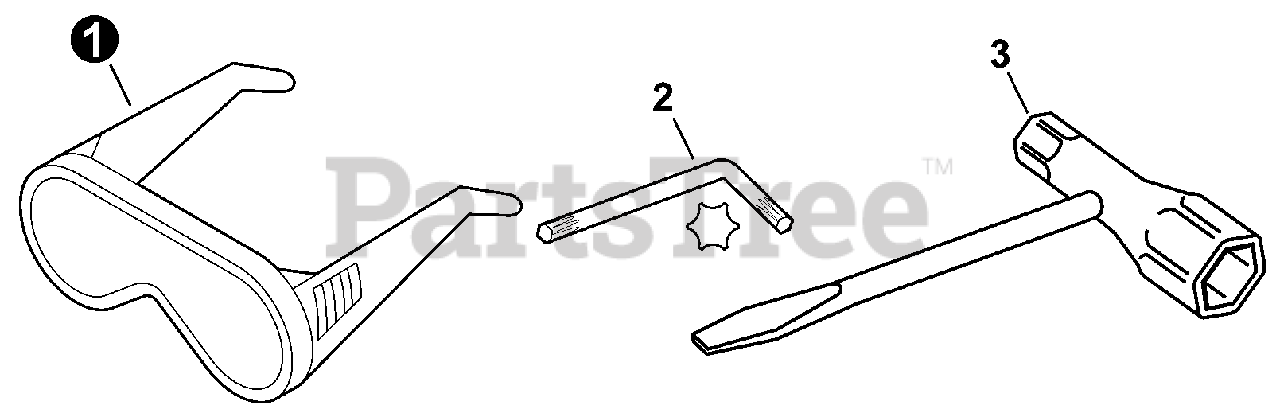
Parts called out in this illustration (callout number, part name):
1	GLASSES, SAFETY
2	WRENCH, ALLEN T27 80×30
3	T-WRENCH 10×19 MM
